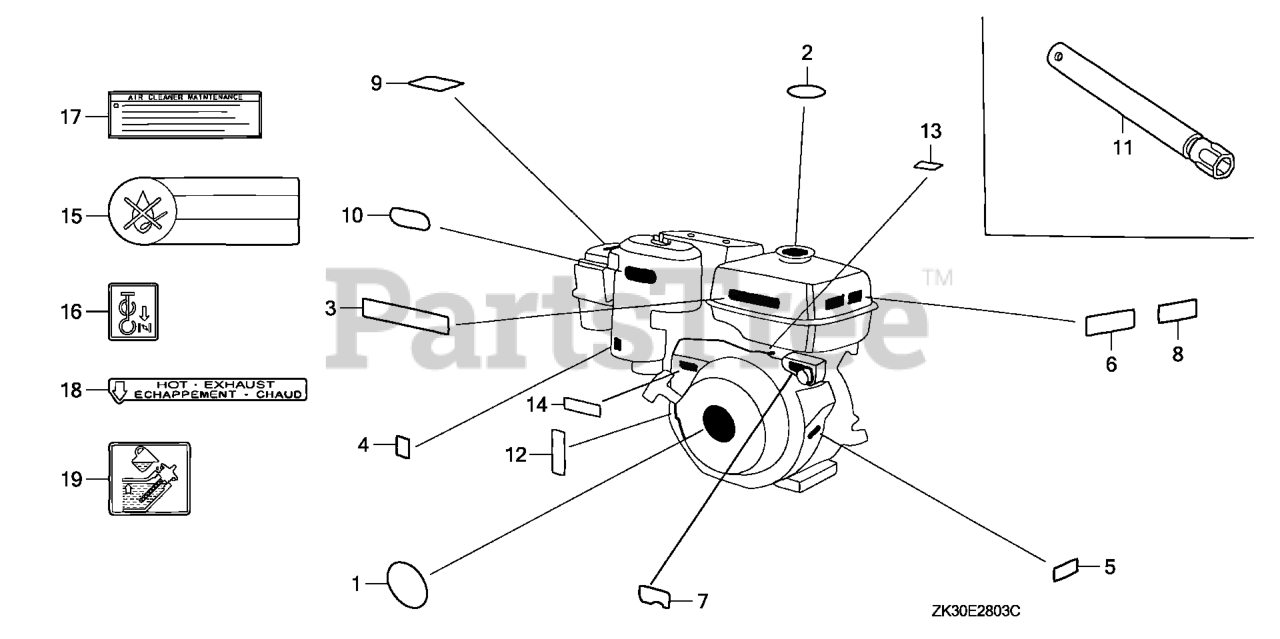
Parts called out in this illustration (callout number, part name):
1	EMBLEM (GX340)
3	LABEL, CAUTION (ENGLISH, ETC.)
4	MARK, CHOKE (EXTERNAL)
8	MARK, OIL ALERT (ENGLISH)
